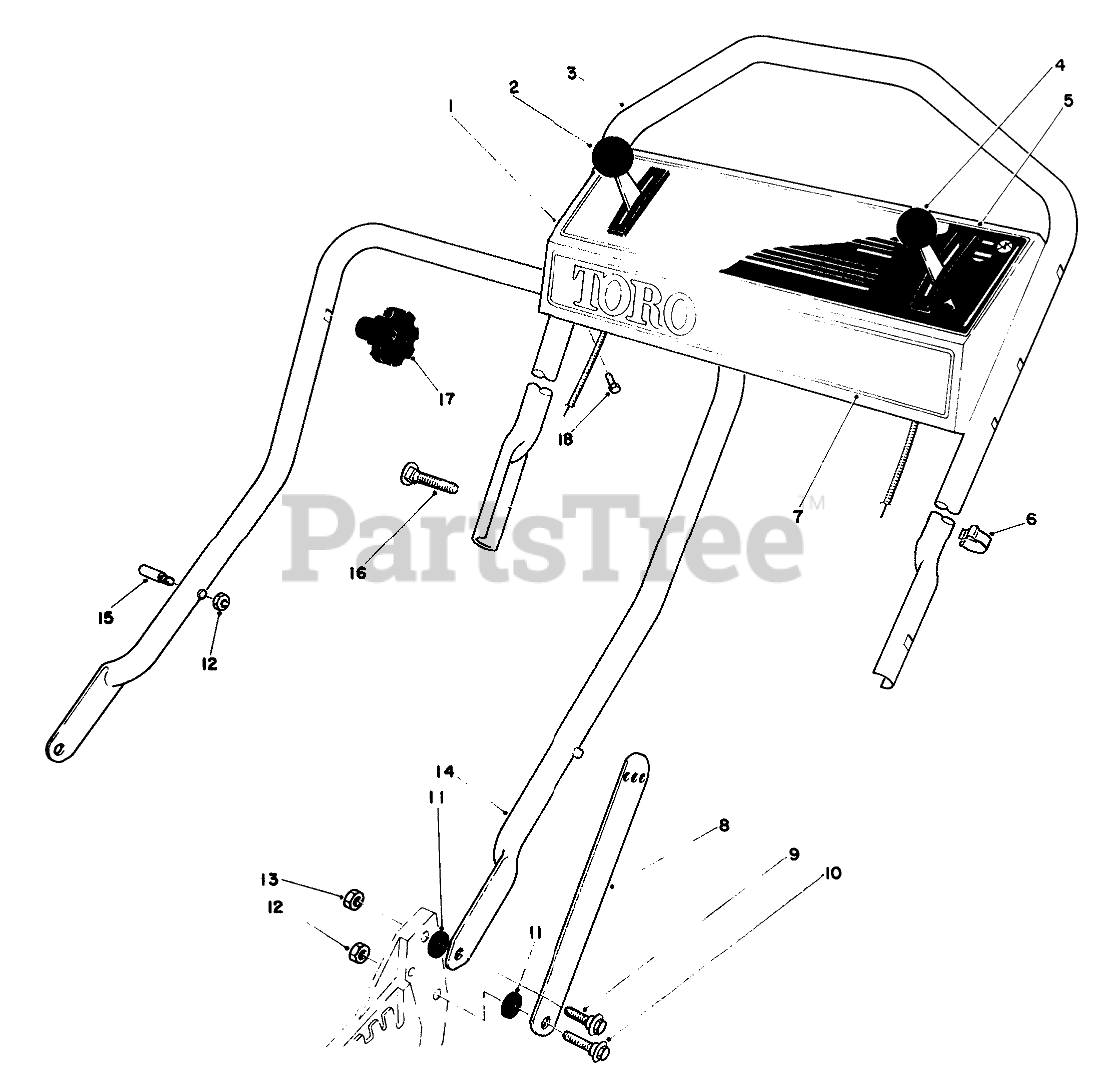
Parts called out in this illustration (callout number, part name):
1	Panel-Control (Incl. Ref. #5)
2	GROUND SPEED CONTROL
3	Handle-Upper
4	SERVICE THROTTLE CONTRO
5	Decal-Instruction Panel
6	BOWDEN CLIP
7	Decal-Toro
8	Handle Latch
9	SCREW-SHOULDER
10	SCREW-SHOULDER
11	SPACER
12	NUT-LOCK, NI
13	NUT-LOCK, NI
14	Handle-Lower
15	HANDLE PIN
16	5/16-18 X 2 HNDLE SCREW
18	SCREW-HWHTF
